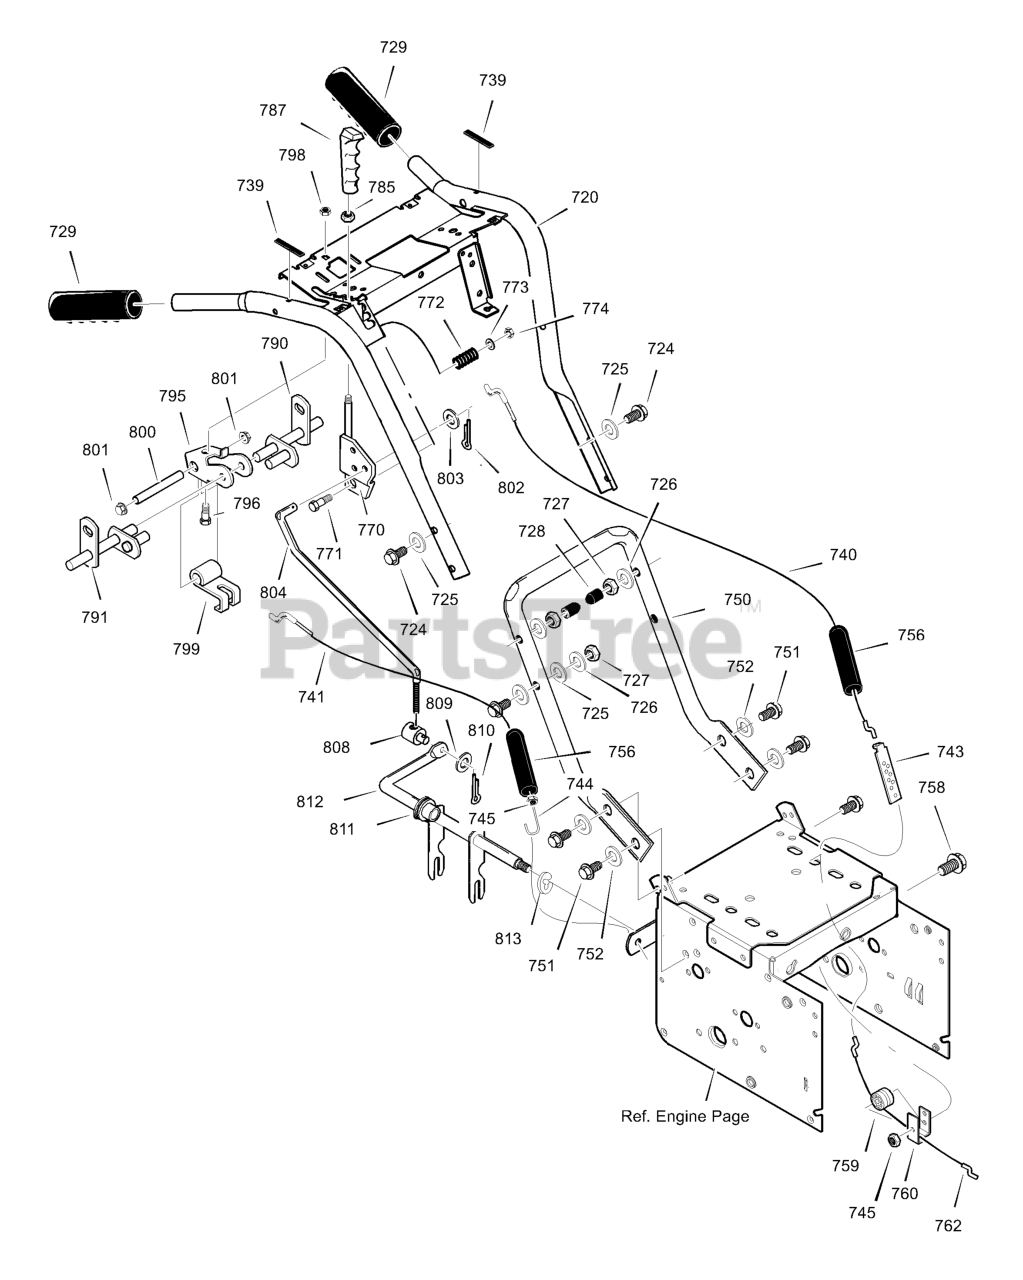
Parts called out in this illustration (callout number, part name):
720	ASSY, HANDLE
724	SCREW
725	WASHER, FLAT
726	WASHER
728	STOP, PLASTIC
729	GRIP, HANDLE
739	BUMPER
740	CABLE, CLUTCH
741	CABLE, CLUTCH
743	BRKT, CABLE ADJ
744	SPRING, CLUTCH
745	NUT, HEX
750	HANDLE, LOWER
751	SCREW
752	WASHER, SPTLK
756	BOOT, CABLE
758	BOLT, HEX
759	SPOOL, CABLE
760	BRKT, SPOOL
762	CABLE, DRIVE
770	BRACKET, SHIFT
771	SCREW
773	WASHER, FLAT
774	NUT, HEX
785	NUT, HEX
787	KNOB, SHIFT
790	ROD, ASSY LH
791	ROD, ASSY RH
795	BRACKET, CAM
796	SCREW
798	NUT, NYLOCK
799	CAM LOCK
800	PIN, SPRING PIVOT
801	NUT, PUSH ON
802	PIN, COTTER
803	FLATWASHER
804	ROD, SPEED CTRL
808	NUT, TRUNNION
809	WASHER
810	PIN, COTTER
811	BEARING, FL
812	ROD, YOKE
813	RETAINER, RING
